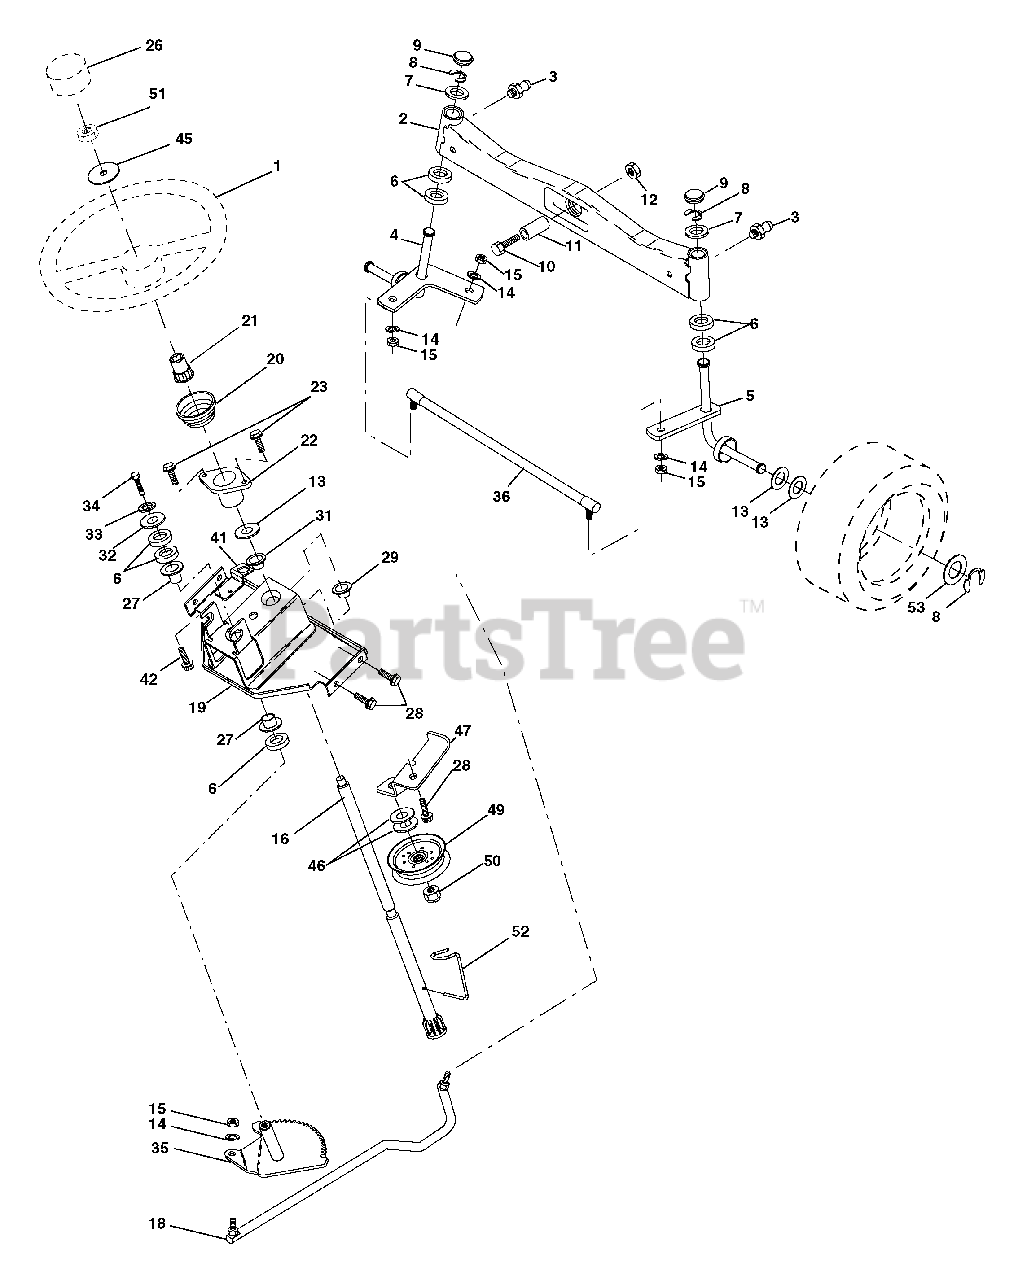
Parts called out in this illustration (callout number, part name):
1	Wheel, Steering
2	Axle Asm., Front
3	Fitting, Grease
4	Spindle Asm, LH
5	Spindle Asm., RH
6	Bearing, Race Thrust Harden
7	Washer 25/32 x 1-5/8 x 16 Ga.
8	Ring, Klip #T5304-75
9	Cap, Spindle
10	Bolt, Fin Hex 5/8-11 x 2-3/4
11	Spacer Brg Axle Front 1.570
12	Nut, Lock Flange 5/8-11 unc
13	Washer 25/32 x 1-1/4 x 16 Ga.
14	Washer, Lock Hvy Hlcl Spr 3/8
15	Nut Crownlock 3/8-24
16	Shaft Asm., Steering
18	Draglink, Vgt
19	Support Asm., Steering Vgt
20	Boot Steering
21	Adapter, Wheel Steering
22	Bushing, Strg.
26	Cap , Wheel Steering
27	Bearing, Col. Strg.
28	Screw 3/8-16 x 3/4
29	Bearing, Flange
31	Bushing, Nyliner Snap
32	Washer 11/32 x 1 x 10 Ga.
33	Washer, Lock Hvy Hlcl Spr 5/16
34	Bolt, Hex Hd 5/16-18 x 3/4
35	Gear, Sector Steering
41	Bracket Switch Inerlock VGT97
42	Screw 5/16-18 x 1/2
45	Washer 9/16 ID x 2-3/8 OD 12 G Zin
46	Washer 13/32 x 1 x 10 Ga.
47	Bracket Asm. Idler
49	Pulley Idler Flat
50	Nut Lock Flg 3/8-16 unc
51	Nut Hex Jam Toplock 1/2-20 unf
52	Clip Steering .750
53	Washer Harden .793 x 1.63 x 060
